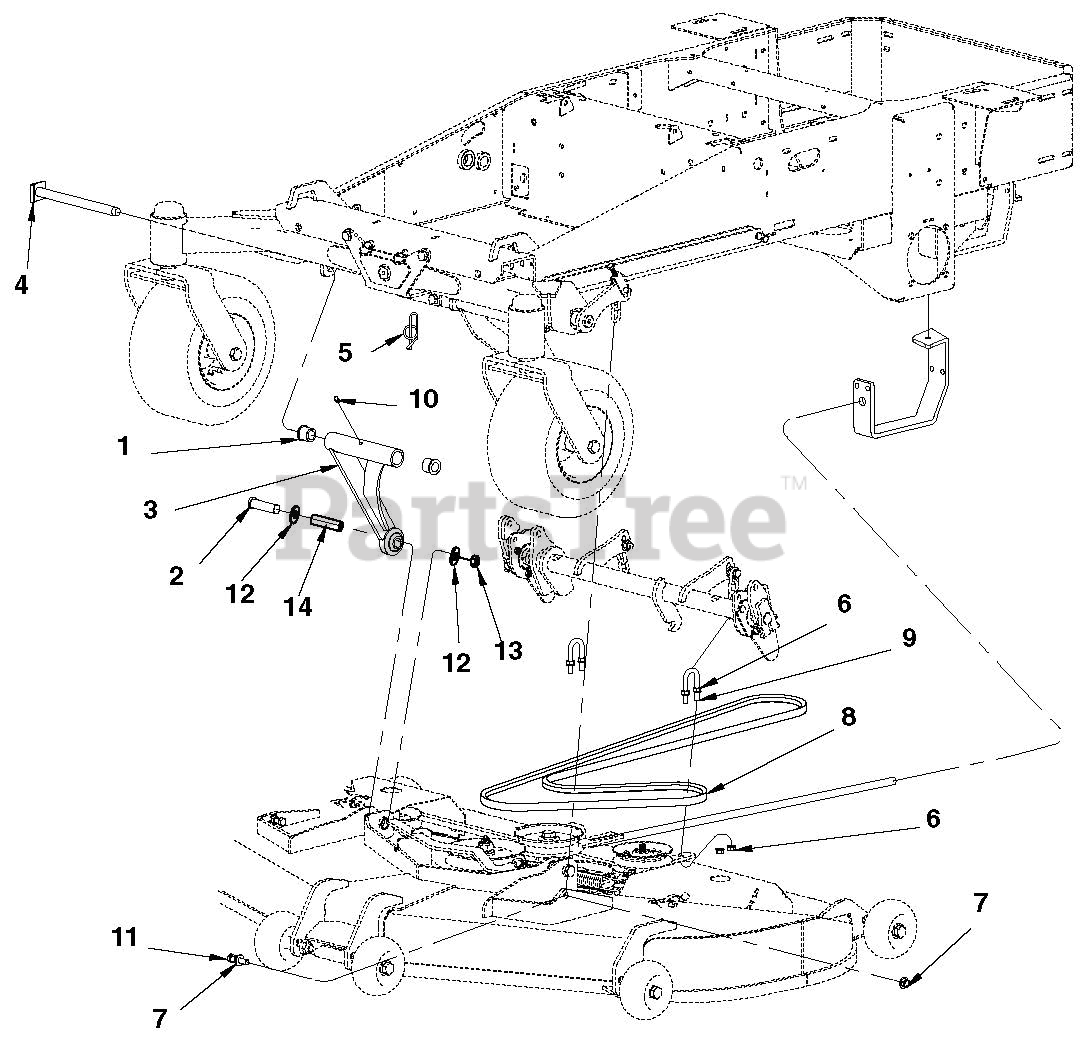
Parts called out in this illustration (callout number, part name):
1	BRG, FLG .750X1.13X1.00
2	BOLT, 1/2-13X3.50 HEX 5 Y
3	WLDT, DECK PULL 11.5
4	PIN, PVT .750X9.75X9.20 XDRL U
5	RING, RUE .750 X .080 X 2.081
6	LOCKNUT, 3/8-16 WHIZ Y
7	LOCKNUT, 7/16-14 WHIZ Y
8	BELT, HB 114.9 EL AMD
9	U-BOLT, RD 1.00X3.00X3/8-16 Y
10	FTG, 1/4-28 STRGT GREASE ZERK
11	BOLT, 7/16-14X1.75 HEX 5 Y
12	WASHER, .500 REG FLAT Y
13	LOCKNUT, 1/2-13 CROWN Y
14	TUBE, RD .750 X.125W X 2.469
